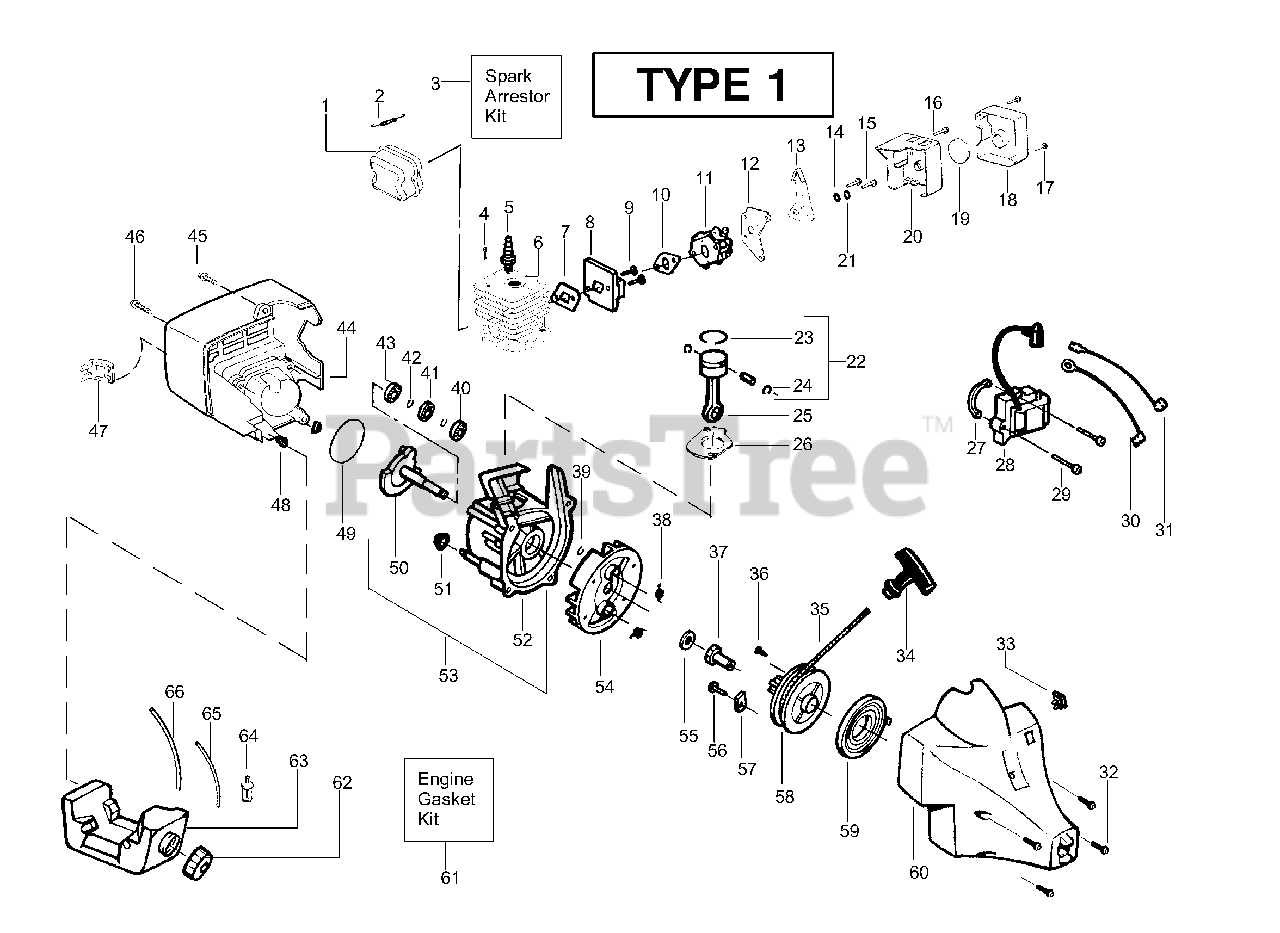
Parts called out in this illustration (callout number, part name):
1	Kit - Muffler
2	Muffler Spring
3	Kit-Spark Arrestor
4	Screw-Cylinder
5	Spark Plug (RCJ 8Y)
6	Kit - Cylinder
7	Gasket-Cylind./Carb.
8	Kit - Carb. Adaptor
10	Gasket-Carb.
11	Kit - Carburetor Ass'y Walbro-(WA-226)
11	Kit - Carburetor Ass'y Zama-(C1U-W7)
12	Choke Plate Mounting
13	Choke Lever
18	Cover-Air Box
19	Foam-Air Filter
21	Spacer-Choke
22	Kit - Piston
23	Piston Ring
24	Retainer-Piston Pin
25	Assy-Connecting Rod
26	Gasket-Cylinder
27	Spacer-Module
28	Ignition Module
30	Assy-Ground Wire
31	Assy-Leadwire
32	Screw
33	Kit-Momentary Switch
34	Handle-Starter
35	Kit - Rope
37	Coupling-Drive
38	Spring-Starter Dog
39	Retain. Ring-C'shaft
40	Bearing-Outer
41	Seal-C'case
42	Retainer Ring-C'case
43	Bearing-Inner
46	Screw
47	Guard-Muffler
48	Isolator-Shroud
49	O-Ring-C'case/Shrd
50	Assy-Crankshaft
51	Isolator-Crankcase
52	Assy-Crankcase
53	Assy-C'case & C'shaft
54	Assy-Flywheel
55	Washer-Flat
57	Retainer-Can
58	Kit-Starter Pulley
59	Spring-Starter
60	Assy-Fan Housing
61	Kit-Engine Gasket
62	Assy-Fuel Cap
63	Assy-Fuel Tank
64	Assy-Fuel Pickup
65	Kit-Fuel Line
66	Kit-Fuel Line
